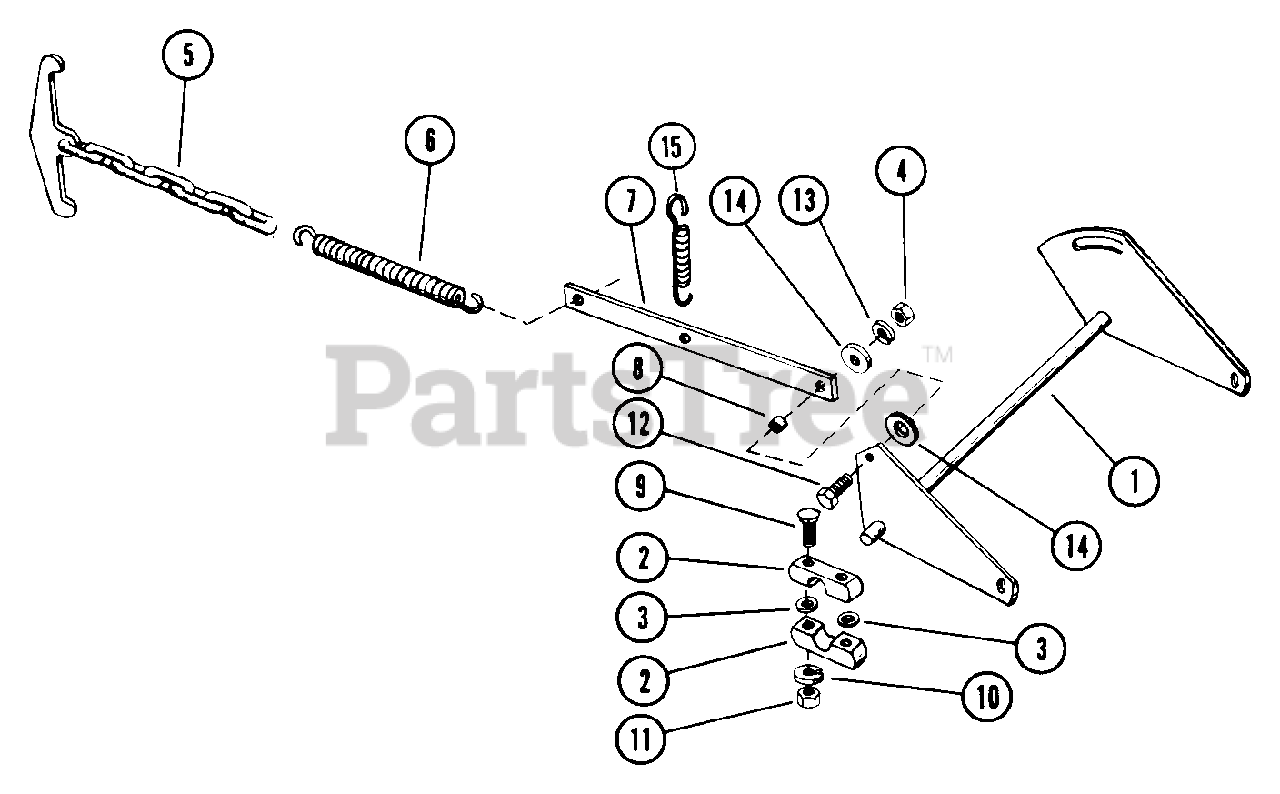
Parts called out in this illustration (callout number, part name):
1	CENTER ROCKSHAFT
3	WSHR-FL-STL .406X.750X.005
4	NUT-HEX .250-20 PL
6	SG-TENS .156X1.062X8.68 WLD ??
8	SPACER .269X.375X.343
9	BLT-RDHDSQNK .38-16X2.25 SHTPL
10	WSHR-LK .375X.094 MED PL
11	NUT-HEX .375-16
12	BLT-HEX .25-20X1.00 GR2
13	WSHR-LK .250X.077 HVY PL
14	WSHR-FL-STL.281X.62X.065 PL
15	SG-TENS .035X.45X2.75 WLD 3.5
